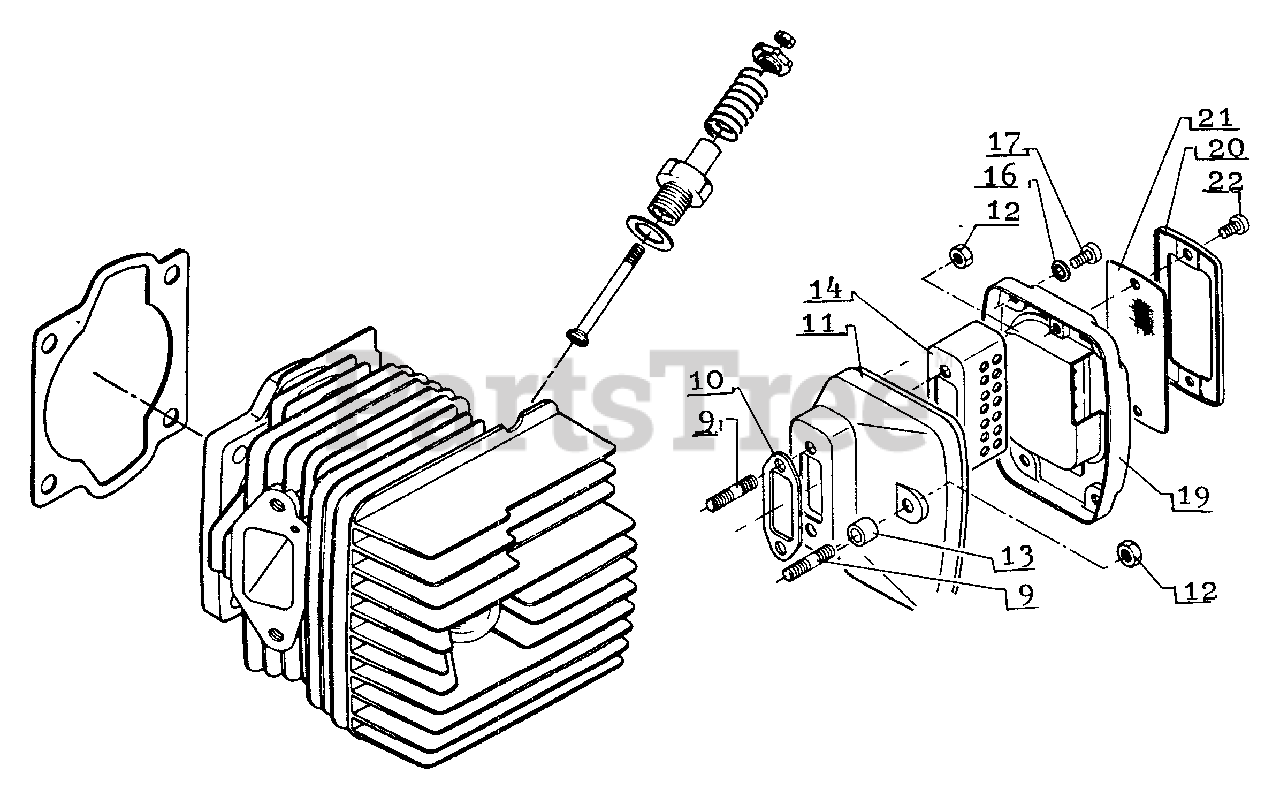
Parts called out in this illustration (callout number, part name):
9	STUD
10	GASKET, EXHAUST
11	MUFFLER
12	LOCKNUT - 6
13	SPACER
14	BAFFLE, MUFFLER
16	WASHER, LOCK 5 MM
17	SCREW 5×8
19	LID, MUFFLER
20	SCREEN, SPARK ARRESTER
21	RETAINER, SCREEN
22	SCREW 5×8
